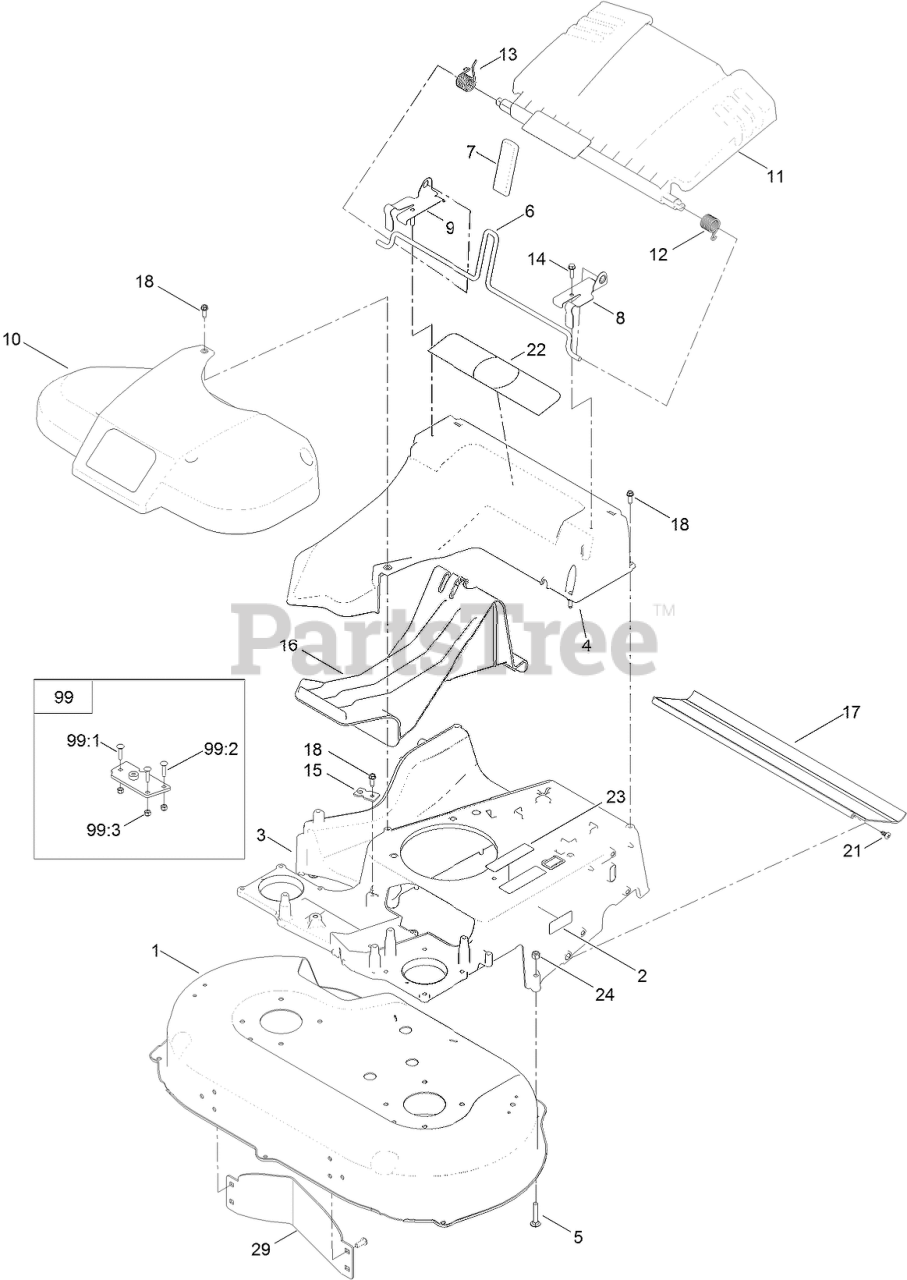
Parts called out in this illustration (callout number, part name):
1	HOUSING ASM
2	DECAL-LOCATION, SERVICE DEALER
4	CHUTE
5	SCREW-CARR
6	ROD-RELEASE, HANDLE
7	GRIP-LEVER
8	BRACKET-DOOR, LH
9	BRACKET-DOOR, RH
10	BELT COVER ASM
11	REAR DEFLECTOR ASM
12	SPRING-TORSION
13	SPRING-TORSION
14	SCREW-HWH
15	BRACKET-CABLE, TRACTION
16	PLUG-MULCH
17	SHIELD-TRAILING
18	SCREW-HWHTF
21	SCREW-PTH
22	DECAL-POSITION, HANDLE
23	DECAL-ARRESTER, SPARK
24	NUT-LOCK, NI
29	BAFFLE-CONTROL
99	FRAME PLATE KIT
99:1	PLATE-FRAME
99:2	SCREW-CARR
99:3	NUT-LOCK, NI
